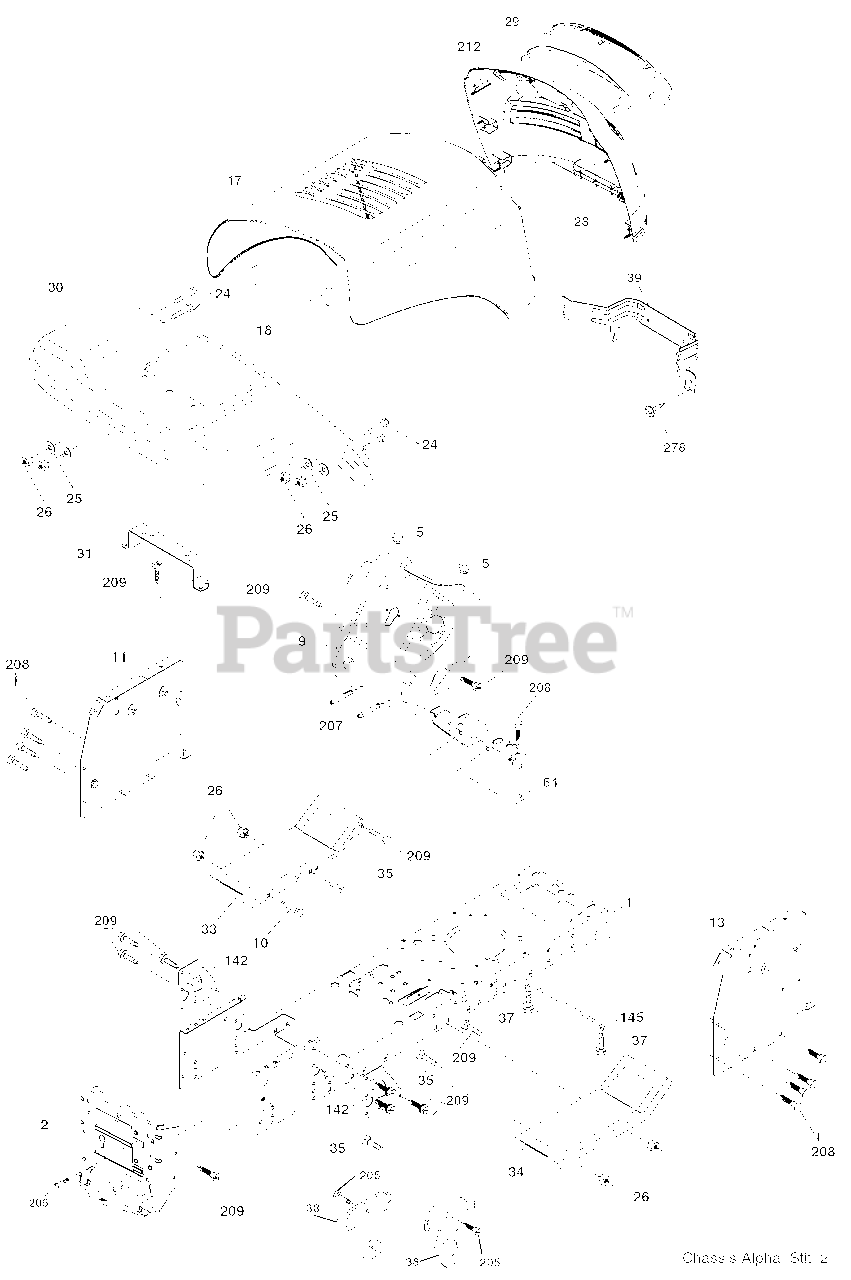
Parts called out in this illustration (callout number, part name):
1	Chassis
2	Drawbar, Stretch
5	Bumper, Hood/Dash
9	Dash
10	Bolt, Carriage 3/8-16 x 1
11	Panel Dash LH
13	Panel Slkscr Dash RH
17	Hood
18	Bumper Hood
24	Bolt Fin Hex 3/8-16 unc x 1 Gr. 5
25	Washer 13/32 x 13/16 x 12 Ga.
26	Nut Lock Hex w/Ins 3/8-16 unc
28	Grille/Lens Asm
29	Lens Grille Basic Bar
30	Fender
31	Bracket Fender Repl 109873X
33	Footrest Pnt LH
34	Footrest Pnt RH
35	Bolt Rdhd Sht Sqnk 3/8-16 x 3/4
37	Screw Thdrol 5/16-18 x 1/2 TYT
38	Bracket Asm. Pivot Mower
39	Bracket Pivot
64	Dash Lower
142	Plate Reinforcement
145	Rod Pivot Chassis/Hood
205	Screw Thdrol 3/8-16 x 1/2
206	Bolt Shoulder 5/16-18
207	Screw Thdrol 5/16-18 x 1/2
208	Screw Thdrol 3/8-16 x 1/2
209	Screw Hex Wsh Thdrol 3/8-16
212	Insert Lens Reflect
278	Screw #10 x 0.750 Single Lead-Hex
278	Plug Button Blk 359 Dia Choke
278	Plug Dome Plastic
